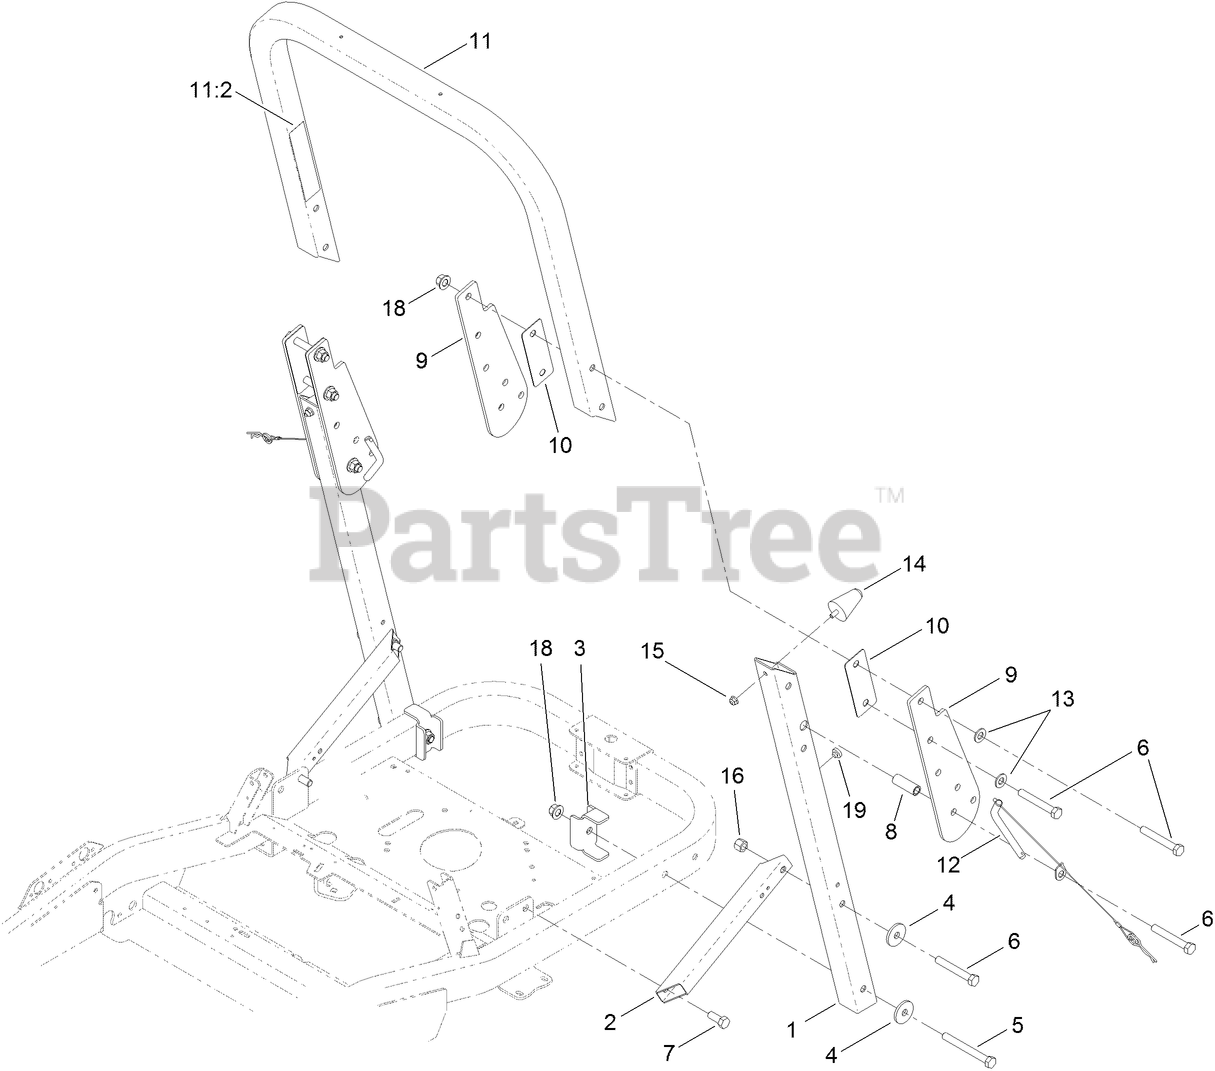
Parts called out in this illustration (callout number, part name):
1	TUBE-ROPS, LOWER
2	TUBE-SUPPORT, ROPS
3	BRACKET-REINFORCING
4	WASHER-THRUST
5	SCREW-HH
6	SCREW-HH
7	SCREW-HH
8	SPACER
9	BRACKET-PIVOT, ROPS
10	SPACER-ROPS
11	UPPER ROPS ASM
11:2	DECAL-WARNING
12	PIN-ROPS W/ LANYARD
13	WASHER-FLAT
14	BUMPER-RUBBER
15	NUT-HF, NI
16	NUT-HEX
18	NUT-LOCK
19	BUMPER
